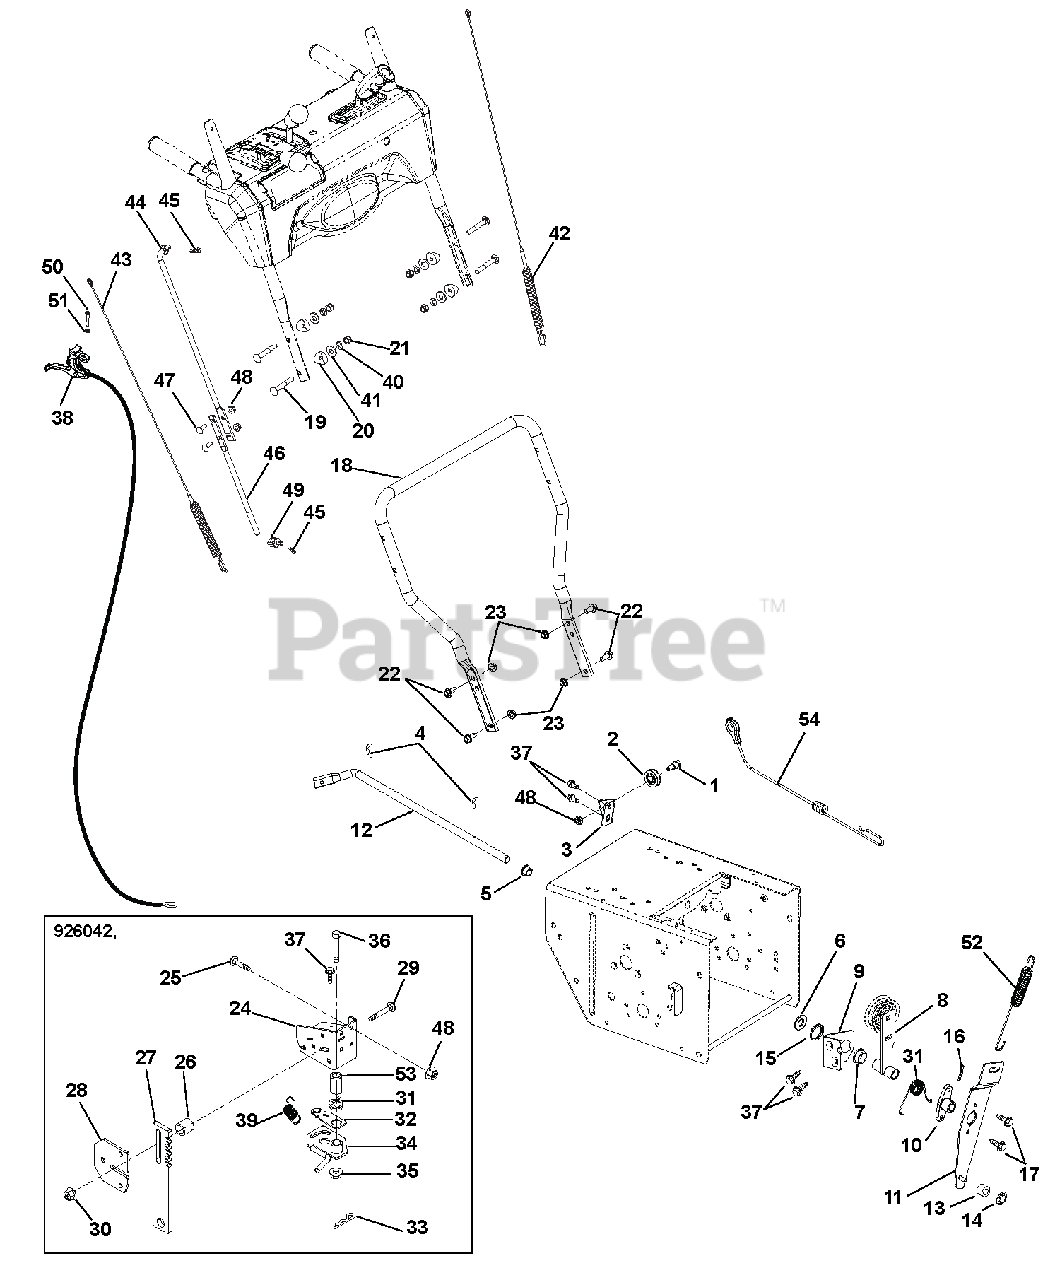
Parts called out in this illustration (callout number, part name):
1	BOLT, SHLDR-.375X.375X.25-20
2	PULLEY, CABLE
3	BRACKET, CABLE PULLEY
4	CLIP, SPRING
5	BUSHING, POLYLINER-.50 SPLIT
6	@WSHR-FL-STL.531X1.06X.095YWZC
7	BUSHING, POLYLINER-.50 SNAPIN
7	BSHG,FLANGE .500X.625X.270X.75
8	ARM, IDLER-TRACTION
9	BRACKET, SUPPORT
10	HUB, BRAKE ARM
11	ARM, IDLER-ATTACHMENT
12	ARM, ATTACHMENT
13	BSHG,SLV .265 X .625 X .375
14	RG-RTNG-EXT .250X.010
15	WAVE WASHER .531X.781X.125FH
15	WAVE SPRING .600X.875X.25FH
16	PIN-ROLL .125X1.00
17	SCR-TAP .25-20X.75 HWH TR YWZ
18	HANDLEBAR, LOWER
19	@BLT-RDHDSQNK .31-18X2.25 G5YZ
20	SPACER, HANDLEBAR
21	@NUT-LK-NYL .312-18 YWZC
22	BLT-SERHFWH .38-16X.75 YWZC
23	@NUT-LK-TOP-FLG .38-16 YWZC
24	BRACKET, HEIGHT ADJUSTER-PRO
25	@BLT-RDHDSQNK .25-20X.75 G5YZ
26	SPACER .50 X .32 X .42
27	STOP, HEIGHT ADJUSTER-PRO
28	PLATE, HEIGHT ADJUSTER
29	@BLT-RHDSHSQNK.31-18X1.25 G5YZ
30	@NUT-LK-TOP-FLG .31-18 YWZC
31	SG-TORS .067X.88
32	ARM, OVERTRAVEL
33	PIN-HAIR INT .06X.18X.77
34	LOCK, HEIGHT ADJUSTER
35	NUT-LK-CTR-FLG .38-16 YWZC
36	@BLT-HEX .38-16X1.75 GR5 YWZC
37	SCR-TAP .25-20X.50 HWH TR YWZ
38	CABLE, TRACK REMOTE
39	SPRING-EXT .047 X .438 X 1.85
40	WSHR-LK .312X.097 HVY YWZC
41	@WSHR-FL-STL.38X.875X.083 YWZC
42	CABLE, UPPER TRACTION
43	CABLE, AUGER (DELUXE & PRO)
44	ROD, SHIFT - UPPER
45	PIN-HAIR INT .08X.18X1.18 YWZC
46	ROD, SHIFT - LOWER
47	@BLT-RDHDSQNK .25-20X.75 G5YZ
48	@NUT-LK-TOP-FLG .25-20 YWZC
49	PIVOT,SHIFT ROD .375-16(TRUNN)
50	SCR-MCH .25-20X1.50 OVAL HD
51	WSHR-LK-INT .250 TH TYA
52	SG-TENS .06X.482X5.35
53	BSHG-SLV .385X.500X1.045
54	CABLE, LOWER TRACTION,SS & PRO
